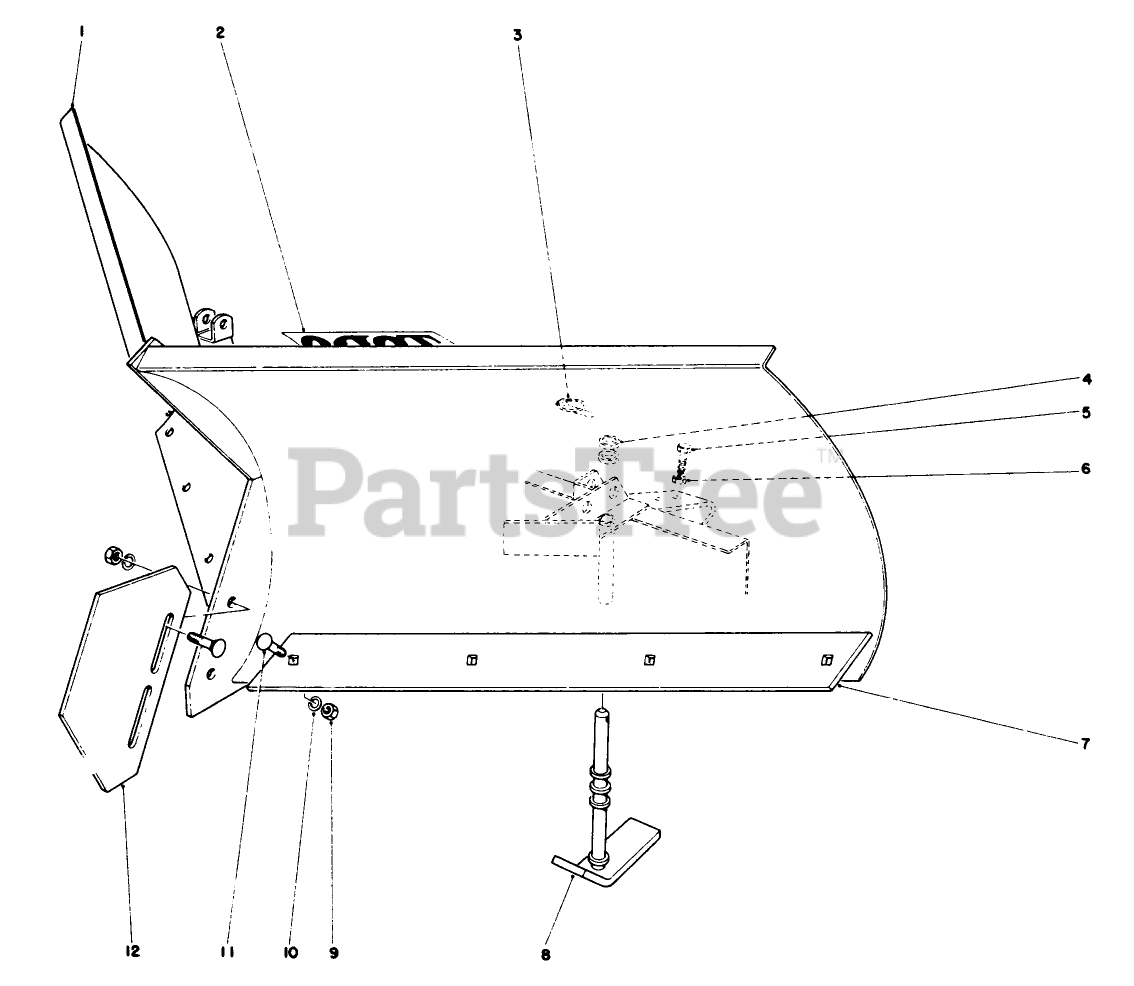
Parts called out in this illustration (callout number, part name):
1	V-Plow
2	Decal
3	PIN-LYNCH
4	SPACER TUBE B
5	SCREW-HH
6	NUT-JAM
7	Blade-Scraper
8	Skid
9	NUT-HH
10	WASHER-LOCK
11	SCREW-CARR
12	Nose Skid
